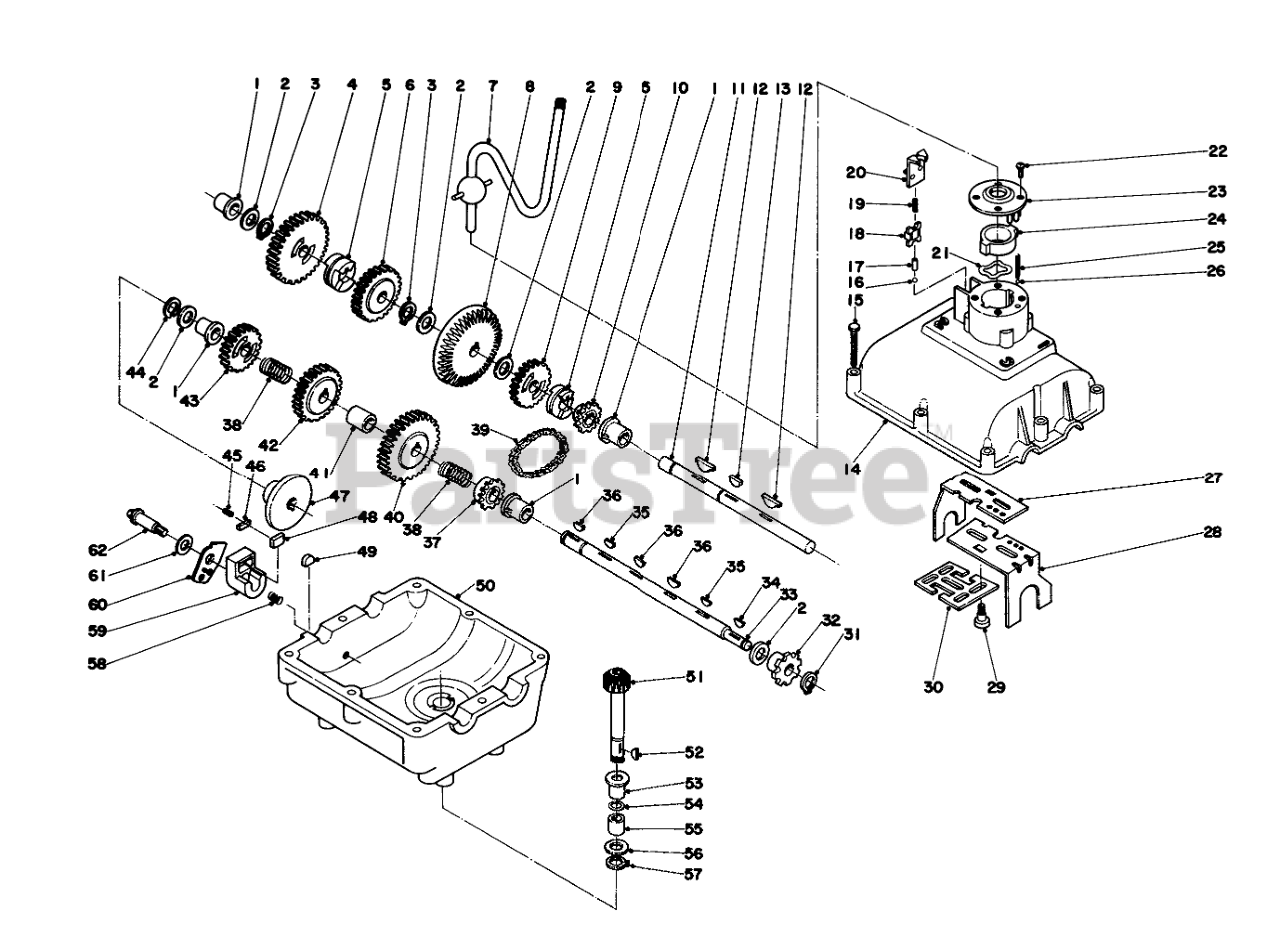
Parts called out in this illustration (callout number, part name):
1	Flange Bearing
2	WASHER KIT
3	Retaining Ring
4	Spur Gear 30T
5	Clutch Collar
6	Spur Gear 25T
7	Shift Lever
8	Bevel Gear 42T
9	Spur Gear 20T
10	Sprocket 12T
11	Drive Shaft
12	Hi Pro Key
13	Woodruff Key
14	Upper Housing
16	Ball Detent
17	Actuating Pin
18	Carrier Contact Assembly
19	Compression Spring
20	Terminal Board
21	Wave Washer
23	Nylon Cover
24	Nylon Insert
25	Detent Spring
26	Detent Ball
27	RH FORK
28	Shifter Fork L. H.
29	Shoulder Screw
30	Lock-Out Plate
31	Retaining Ring
32	Sprocket 8T
33	Output Shaft
34	Woodruff Key
36	Woodruff Key
37	Sprocket 12T
38	Spring Compression
40	Spur Gear 30T
41	Spacer
42	Spur Gear 25T
43	Spur Gear 20T
44	RETAINING RING
45	Set Screw
46	Spacer
47	BRAKE DISC
48	FRICTION PUCK
49	FRICTION PUCK
50	Lower Housing
51	Input Shaft
52	Woodruff Key
53	Flange Bearing
54	Washer
56	Washer
57	RING-Retaining
58	Compression Spring
59	Brake Jaw
60	Actuating Lever L.H.
61	Washer Kit
62	Shoulder Bolt
